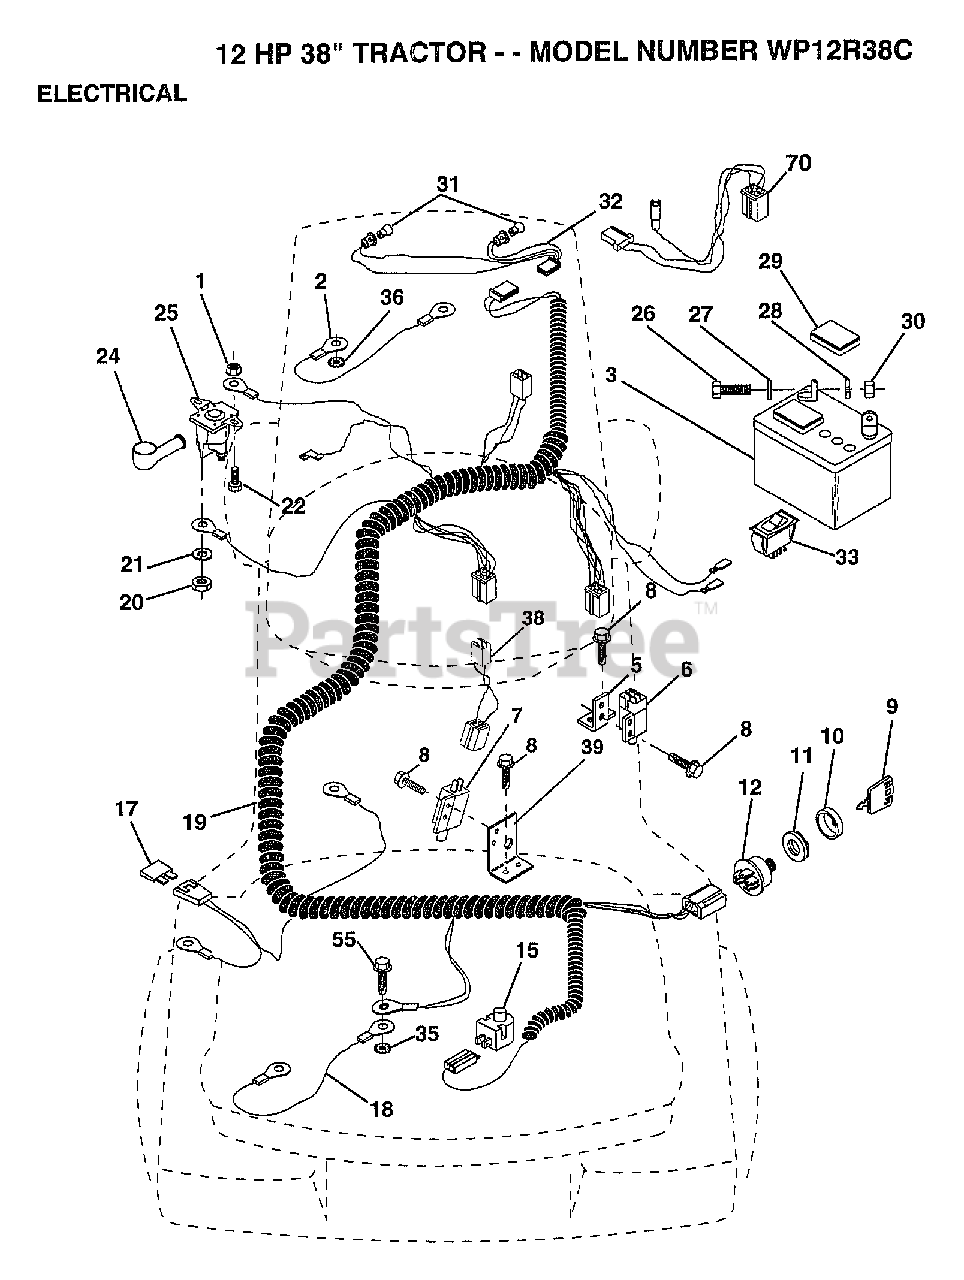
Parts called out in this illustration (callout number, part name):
1	NUT
2	CABLE ASM.
5	BRACKET LT
6	SWITCH INTERLOCKT
7	SWITCH-INTER. GT
8	SCREW
9	KEY MLD GEN DELTA
10	COVER KEY SWITCH
14	WIRE TIE
15	SWITCH SEAT
17	FUSE HYT
18	CABLE ASSY
19	HARNESS.IGN.FEND.
20	NUT
22	BOLT
26	BOLT LT
27	WASHER
28	LOCKWASHER
29	"CAP,BATTERY "
31	HEADLAMP BULB
32	"HARNESS,LIGHT SOC"
33	SWITCH LT
35	LOCKWASHER.5/16.E
36	LOCKWASHER
38	ADAPTER.HARN.SERV
39	BRACKET SWT CLUTC
55	SCREW LT
70	HARNESS ENG DUAL
